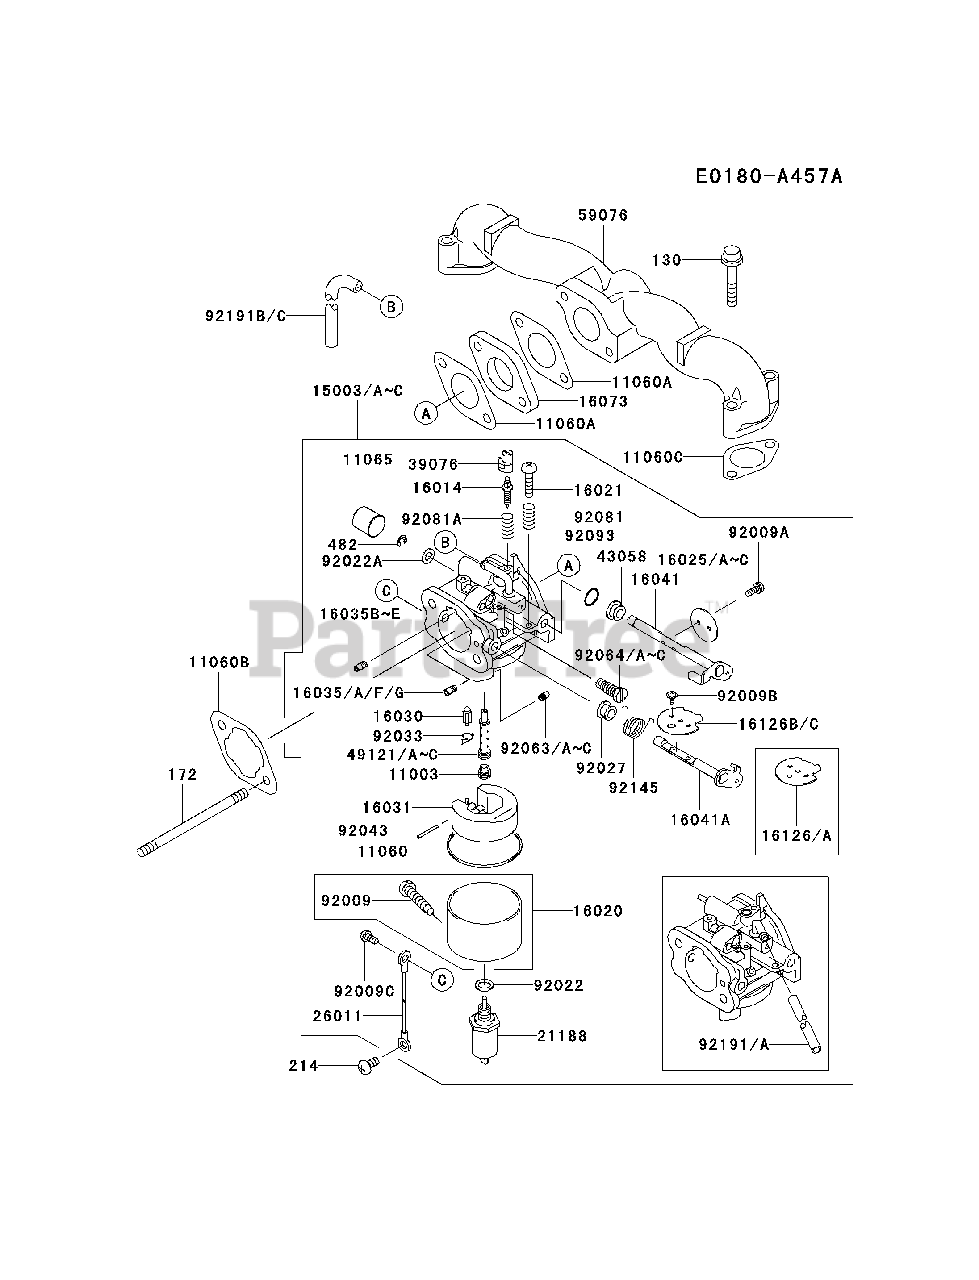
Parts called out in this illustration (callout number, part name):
130	BOLT-FLANGED
172	BOLT-STUD
214	SCREW-PAN+-
482	CIRCLIP-TYPE-E
92191B	TUBE,4.76X7.94X225
